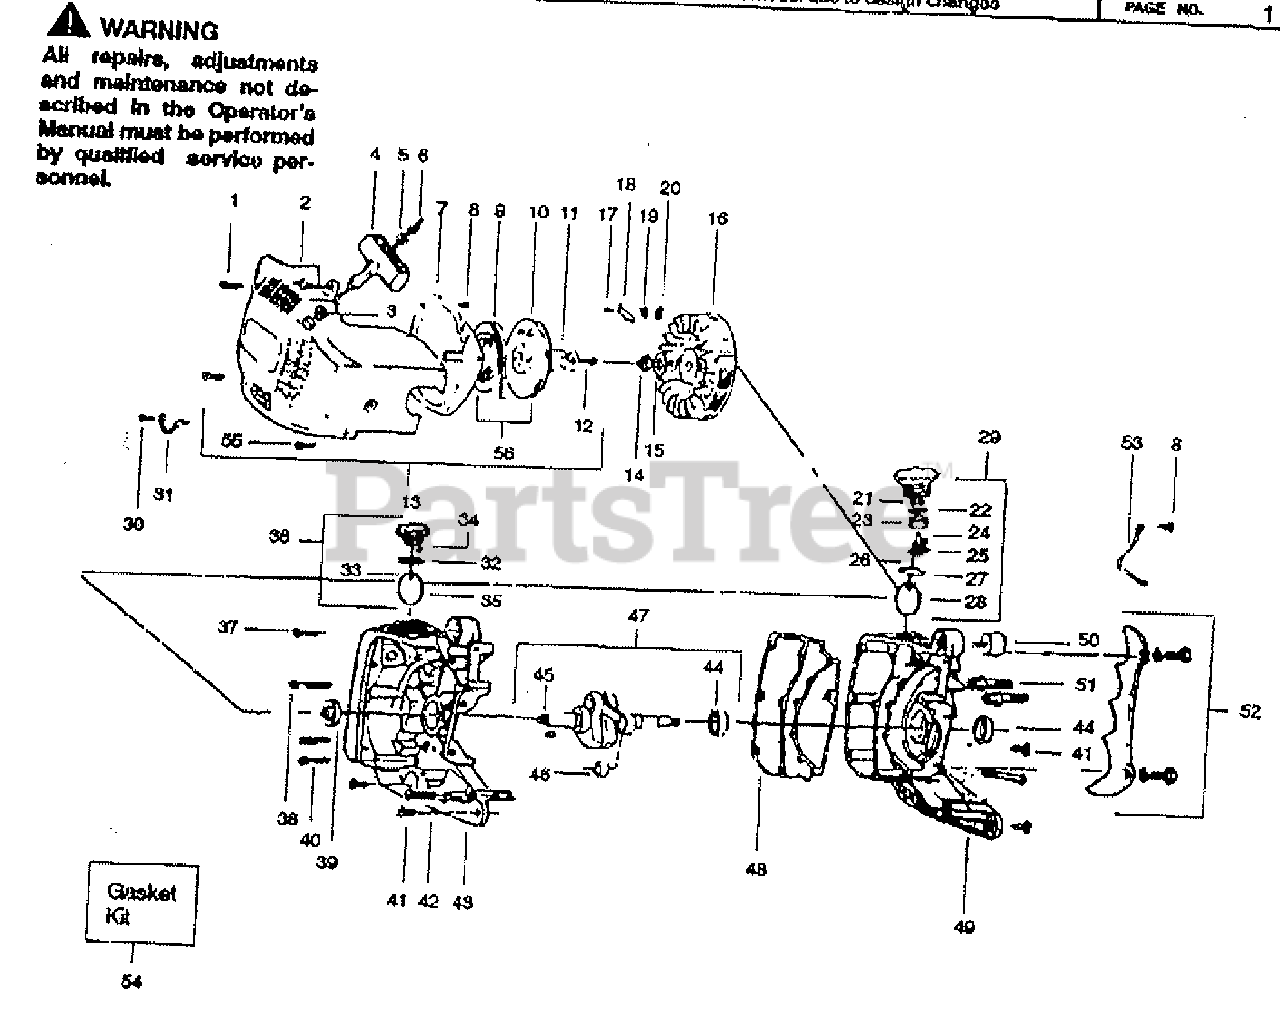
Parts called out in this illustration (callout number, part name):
2	Starter Cover & Shell Assy.
4	Starter Handle
6	Starter Cord
7	Baffle Plate
9	Rewind Spring
10	Starter Pulley
13	Starter Assy.
16	Flywheel
17	Pivot Pawl
24	Umbrella Valve
25	Cover Gas Cap
26	Bead Chain
27	"O" Ring
28	Retainer
29	Gas Cap Ass'y.
31	Retainer Wire
32	"O" Ring
33	Bead Chain
35	Retainer
36	Oil Cap Assy.
43	Crankcase Half
44	Main Bearing
45	Flywheel Key
47	Crankshaft Ass'y.
49	Crankcase Ass'y Drive Side
50	Shock Absorber
51	Bear Mtg. Studs
52	Pivot Grip Kit
53	Ground Wire
54	Gasket Set
56	Pulley & Spring Kit
